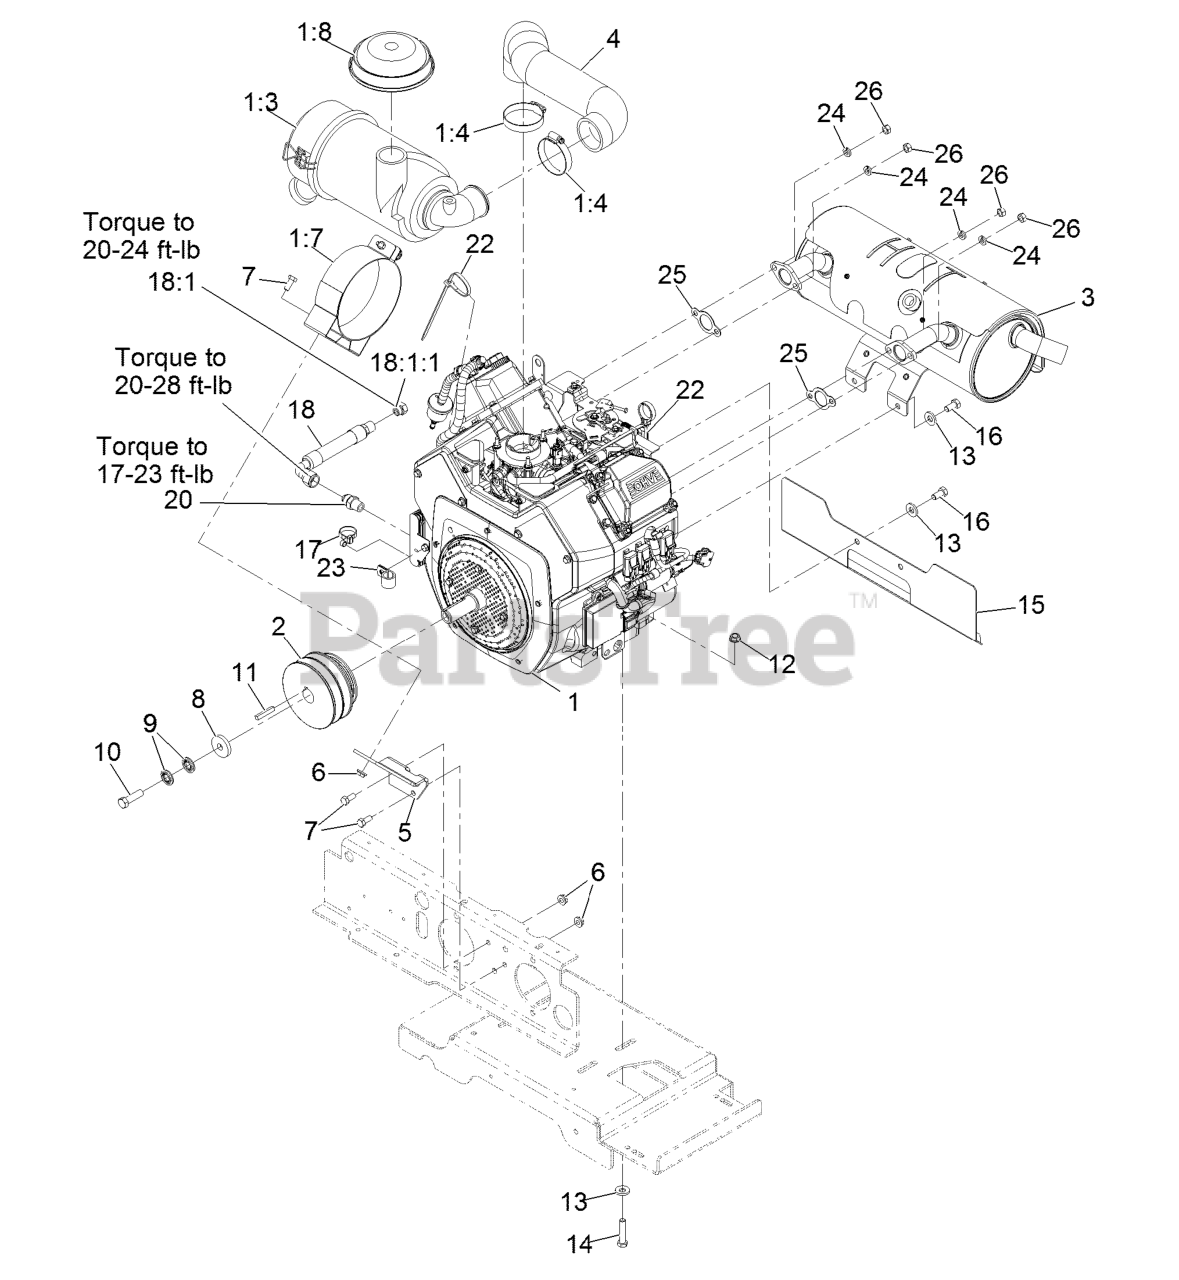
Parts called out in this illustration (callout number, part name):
1:3	AIR CLEANER CANISTER ASM
1:4	CLAMP-HOSE
1:7	BRACKET-FILTER, AIR
1:8	HOOD-CLEANER, 2" AIR INTA
4	HOSE-AIR INTAKE
5	BRACKET-FILTER, AIR
7	SCREW-HH
8	WASHER-CLUTCH
9	WASHER-SPRING
10	SCREW-HH
11	KEY-SQUARE
12	NUT-HHF, WHIZ
13	WASHER-BELLEVILLE
14	SCREW-HH
15	SHIELD-EXHAUST
16	SCREW-HH
17	Tie-Cable
18	OIL DRAIN HOSE ASM
18:1	PLUG-HH
18:1:1	O-RING
20	FITTING-STRAIGHT
22	TIE-PLASTIC
23	CLIP-LOOM
24	WASHER-LOCK
26	NUT-HEX
